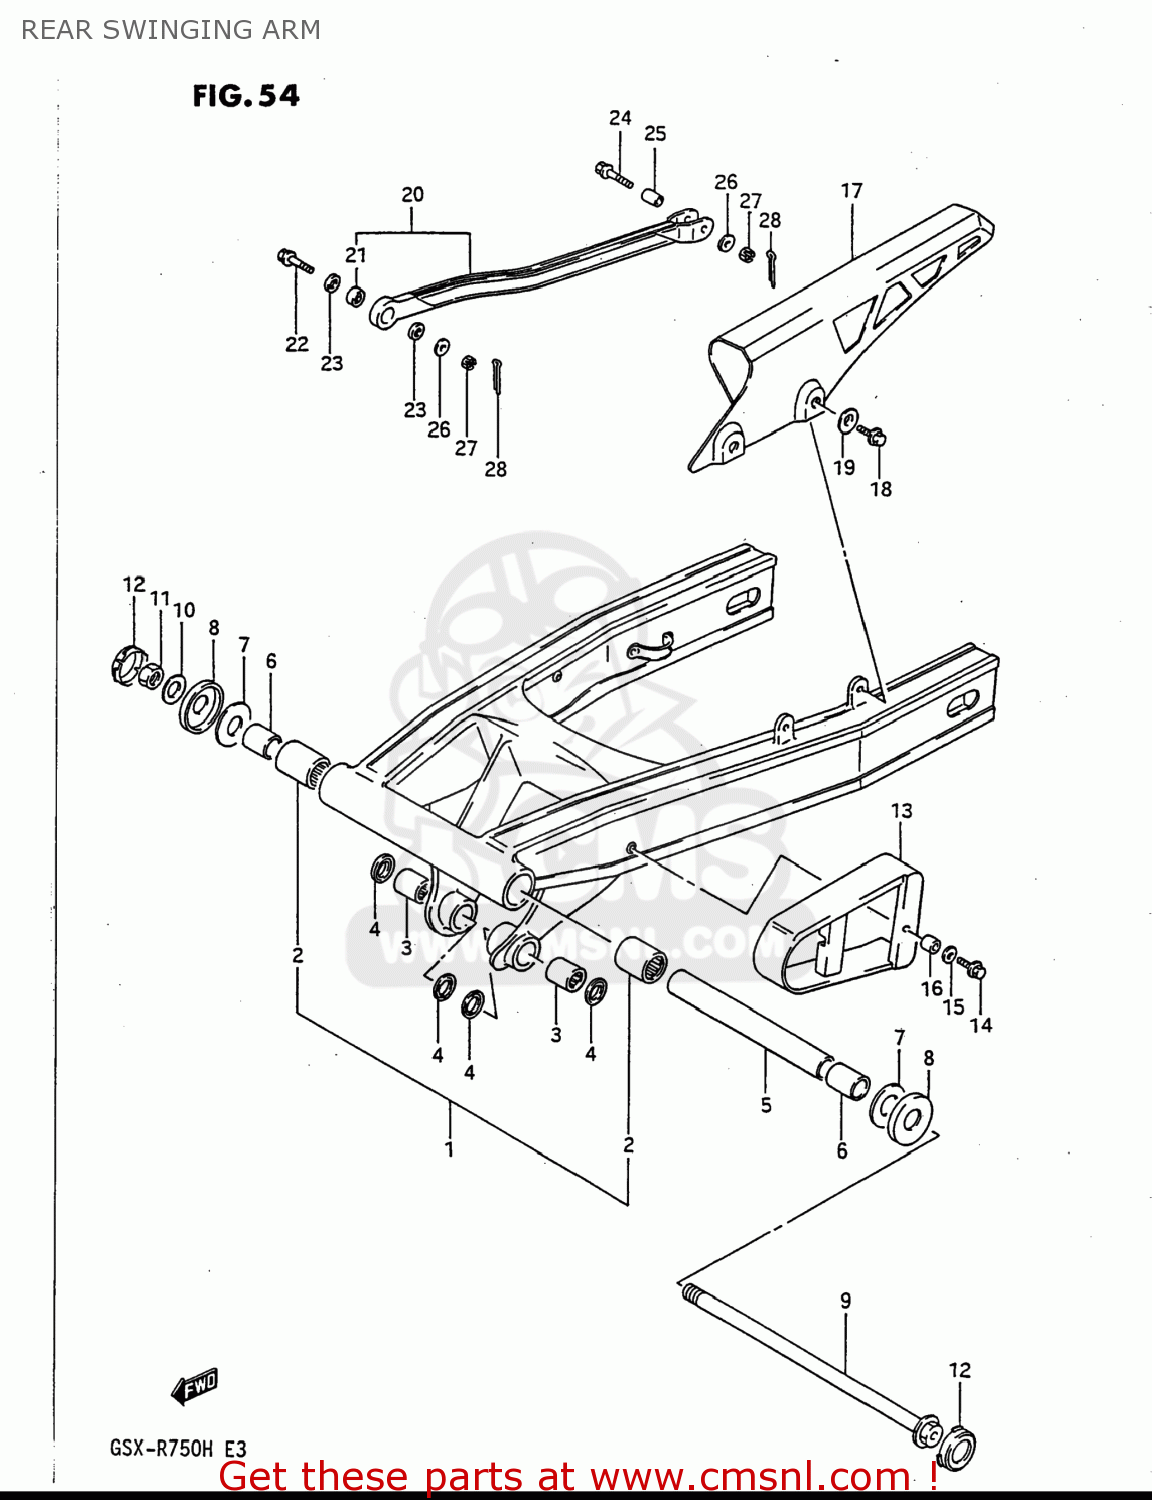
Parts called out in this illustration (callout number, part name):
1	SWING ARM ASSEMBLY,REAR
2	BEARING(22X29X25)
3	ROLLER BEARING (17X24X25))
4	SPACER,REAR CUSHION ROD
5	SPACER,RR SWGARM PIVOT CTR
6	SPACER,RR SWGARM PIVOT BEARING
7	WASHER
8	COVER,RR SWGARM DUST SEAL
9	SHAFT,REAR SWING ARM
10	WASHER(14X27X3)
11	NUT
12	CAP,SWINGINGARM PIVOT
13	BUFFER,CHAIN TOUCH DEFENSE
14	BOLT,M6X1X20
15	WASHER(6.5X16X1.2)
16	SPACER(6.5X8.5X5.8)
17	CASE,CHAIN
18	BOLT
19	WASHER
20	TORQUE LINK SET,REAR
21	SPHERICAL BEARING,TORQUE
22	BOLT(8X38)
23	24
24	BOLT
25	SPACER,RR TORQUE LINK RR
26	WASHER
27	NUT 8MM
28	PIN 20X20
